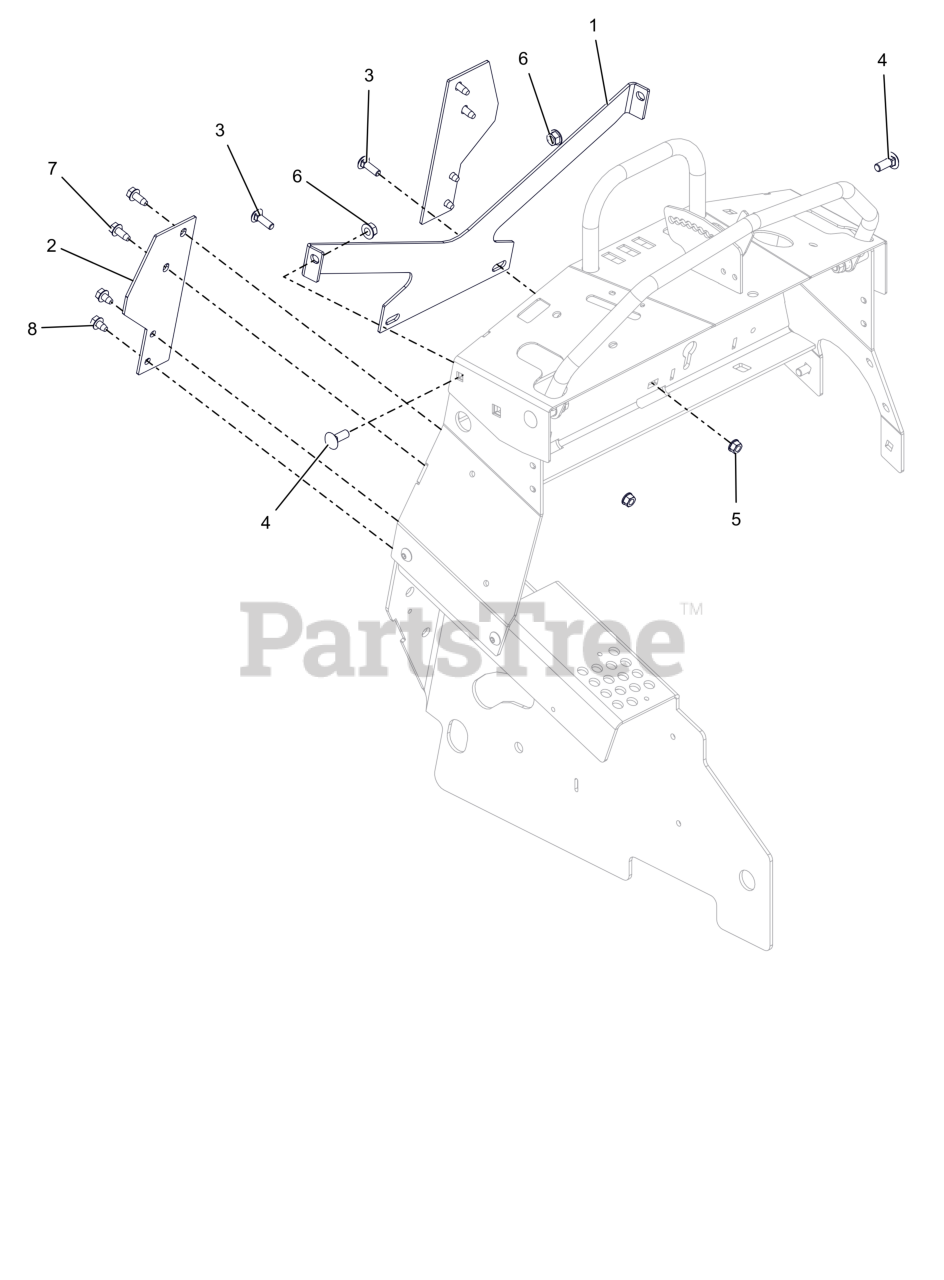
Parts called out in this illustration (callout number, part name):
1	BRKT, UPPER REAR SUPPORT (RED)
2	PLATE, LOWER REAR SUPPORT (RED)
3	BLT,RHSN .31-18X1.00 G5 ZCC
4	BLT, RHSN .38-16X1.00 G5 ZCC
5	NUT,LK-CTR-FLG .31-18 GF ZCC
6	NUT-LK-CTR-FLG .375-16 GF ZCC
7	SCR,TAP .312-18X.75 HWH TR ZCC
8	SCR,TAP .312-18X.50 HWH TR ZCC
